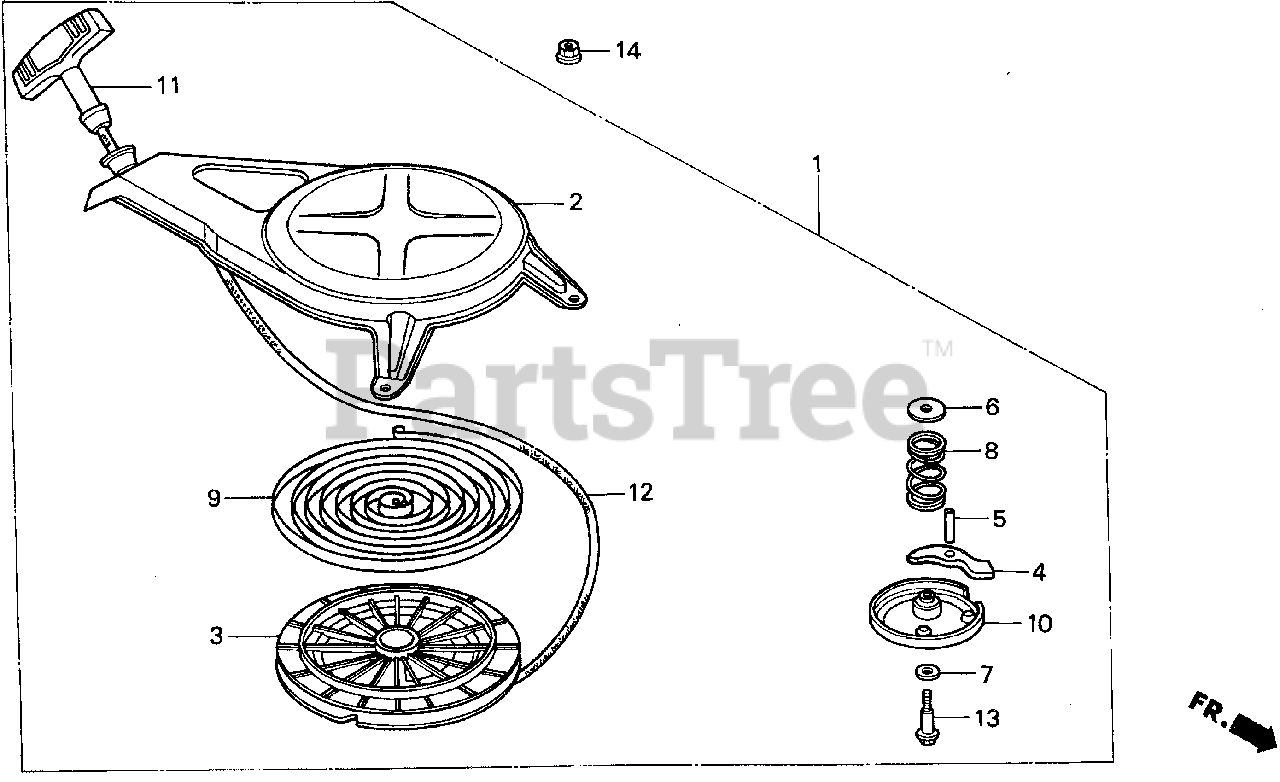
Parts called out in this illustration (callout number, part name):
1	STARTER ASSY., RECOIL (NOT AVAILABLE)
2	CASE, STARTER (NOT AVAILABLE)
3	REEL, STARTER
3	REEL,STARTER
4	RATCHET, STARTER
5	SHAFT,RATCHET
6	PLATE A, FRICTION
7	PLATE B, FRICTION
8	SPRING, FRICTION
9	SPRING, RETURN
10	COVER, REEL STARTER
11	GRIP, STARTER
12	ROPE, STARTER (#4X65")
13	BOLT, REEL COVER
14	NUT, FLANGE (5MM)
